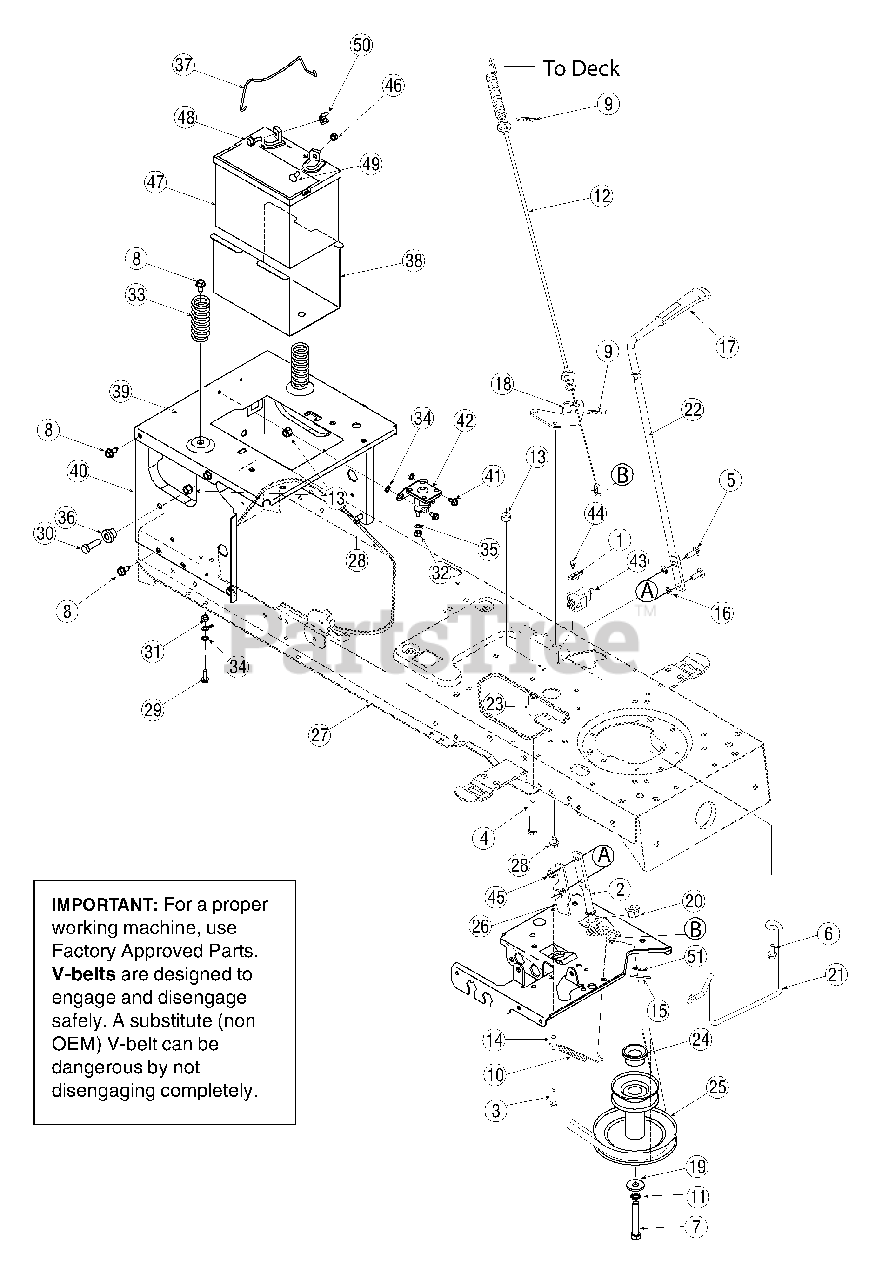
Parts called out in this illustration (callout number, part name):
1	Plate, Switch
2	Lever Assembly, Engagement
3	Screw, 1/4-20 x 1.250
4	Screw, 3/8-16, 2.50
5	Screw, Carriage, 5/16-18, 1.00
6	Screw, 5/16-18 x.750
7	Screw, 7/16-20, 3.25, Gr5
8	Screw, 5/16-12, 0.750
10	Extension Spring,.38OD x 3.9LG
11	Lock Washer, 7/16
12	Deck Engagement Cable
13	Nut, Flange Lock, 3/8-16, Gr F, Nylon
14	Spacer,.260 x.372 x 1.030LG
15	Pin, Cotter, 1/8 x 1.25
16	Nut, Speed,.3125 ID
17	Knob, PTO
20	Bearing, Flange, Hex Split.500 ID
21	Keeper Rod, Belt
23	Spacer,.385 ID x.635 OD x 1.54
24	Spacer, 1.010 x 1.400 x.825
25	Pulley, Engine, 3.56 x 6.12 Diameter
29	Screw, 1/4-20, 0.750
30	Screw, 3/8-16, 1.25, Gr5
31	Nut, Flange Lock, 1/4-20, Gr F, Nylon
32	Nut, Hex, 1/4-20, Gr5
33	Spring, Compression, 1.28 OD x 3.125
34	Washer, Lock, 1/4, External
35	Washer, Lock, 1/4
36	Spacer, Shoulder,.38 x 1.0 x.70
37	Hold Rod, Battery
41	Screw, 1/4-20, 0.50
42	Solenoid, 12V, 100 Amp
43	Switch, Interlock
44	Screw, #10-16,.50
45	Nut, Flange, Lock Nut, 5/16-18
46	Nut, Sems, 1/4-20
47	Battery, 235 CCA
48	Screw, Shoulder,.250 x.15, 1/4-20
49	Screw, Carriage, 1/4-20,.75
50	Nut, Wing, 1/4-20
51	Flat Washer,.344 x.688 x.065
